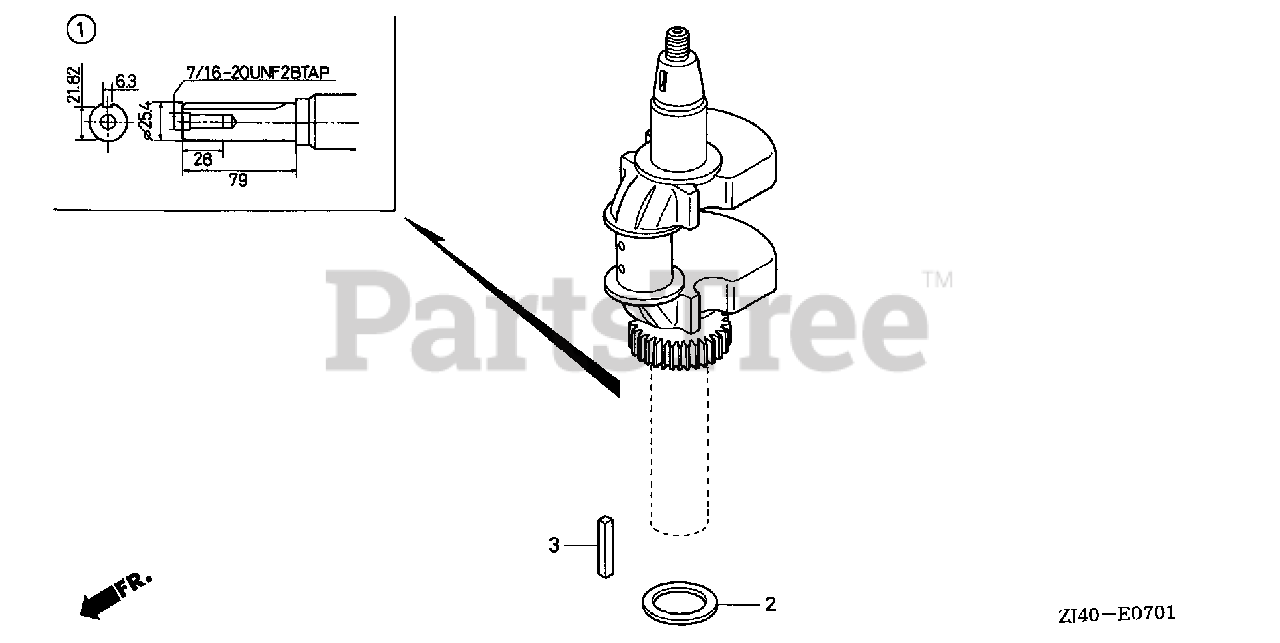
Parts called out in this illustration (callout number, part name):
1	CRANKSHAFT
2	WASHER, CRANKSHAFT THRUST
3	KEY (6.3X6.3X43)
